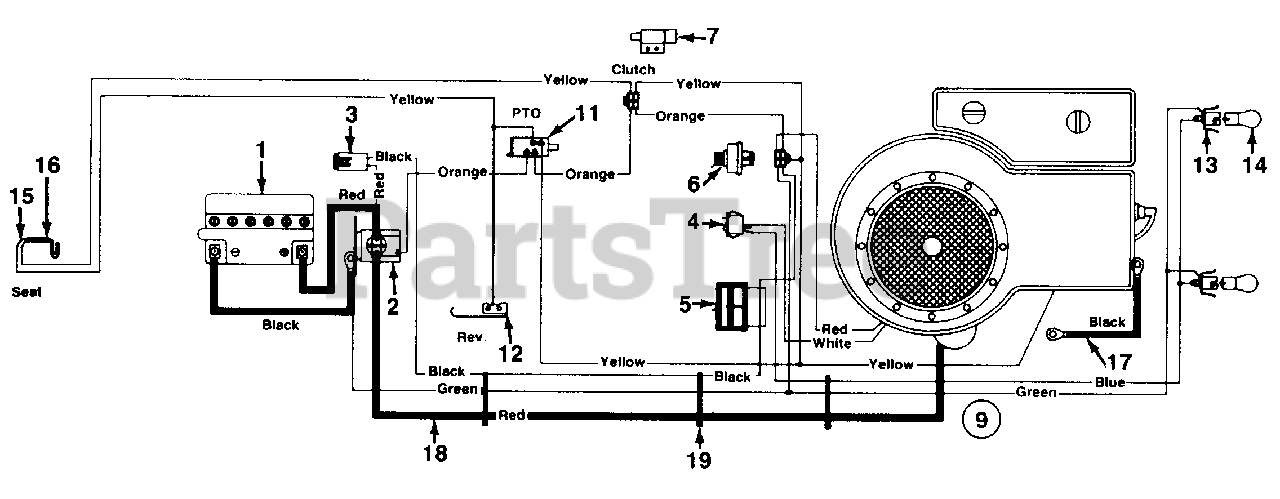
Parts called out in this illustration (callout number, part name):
1	Battery
2	Solenoid
3	Fuse 7.5 Amp
4	Light Switch
5	Ammeter
6	Ignition Switch
7	Safety Switch (Clutch)
9	Wire Harness
11	Safety Switch (Deck)
12	Safety Switch (Reverse)
13	Socket
14	Bulb
15	Safety-Switch (Seat)
16	Safety Switch (Seat)
17	Ground Wire 7.5" Lg.
18	Electric Wire
19	Cable Tie
